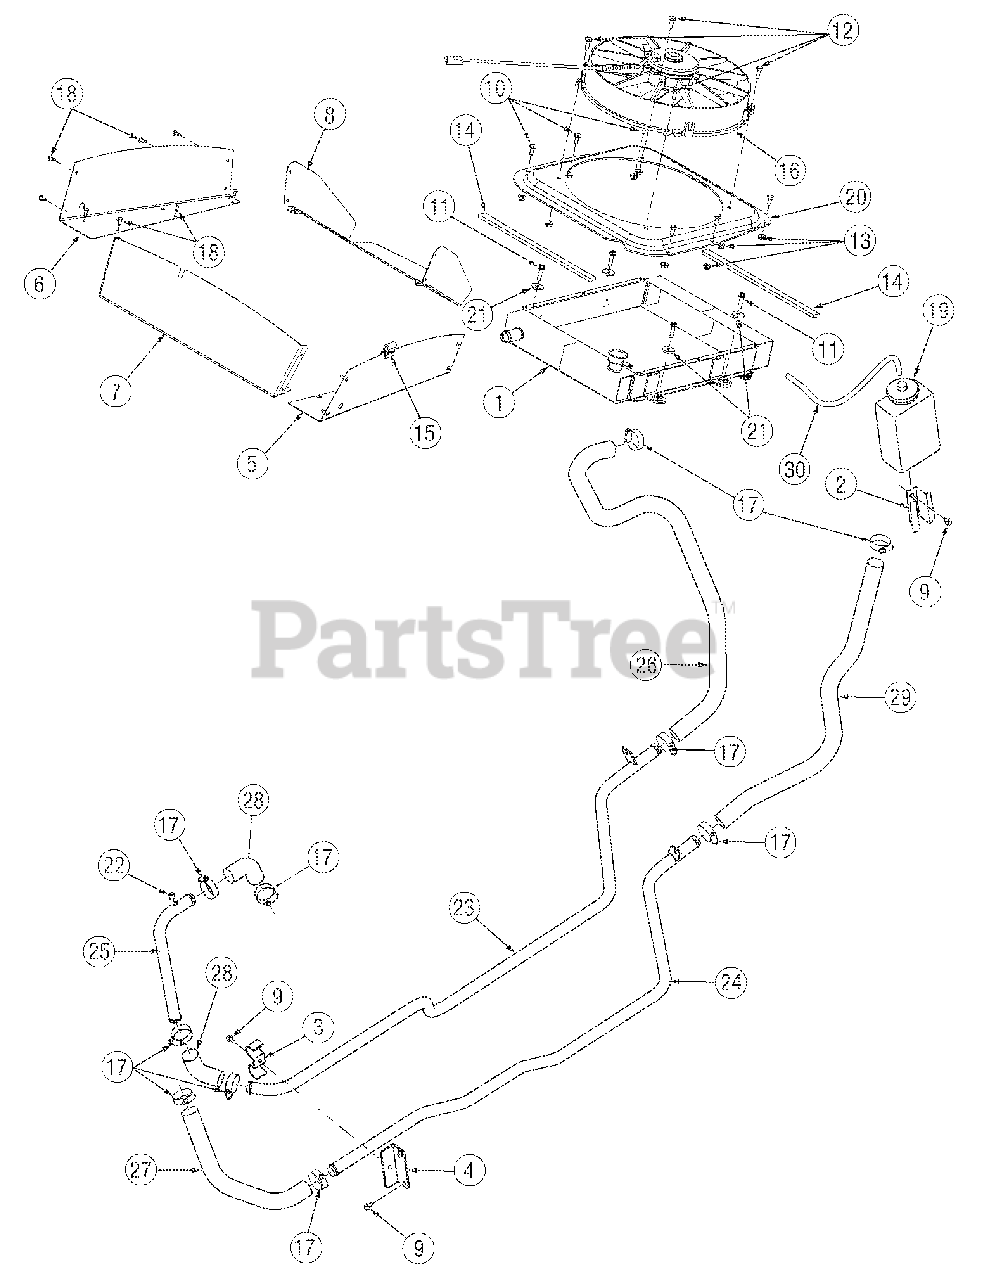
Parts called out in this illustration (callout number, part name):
1	Radiator Asm, zin Core
9	Scr, tt, 1/4-20, 0.500, hxindwsh
10	Hhcs, 1/4-20 x .62 GR5
11	Scr, tt, 1/4-20, 1.000, hxindwsh
12	HHCS, 1/4-20 x .75 GR5
13	Nut, flglk, 1/4-20, grf, nylon
14	Tape, .625 Wide x .25 Thk Foam
15	Heat Baffle Seal
16	Fan, electric, 12v
17	Clamp, hose, adj
18	Pop Rivet 3/16 Dia x .450, sty1
19	Cntnr, over Flow, coolant
20	Shroud, Fan Mount
21	Wash, flat, .265 x .938 x .120
22	Plug, pipe, 1/8-27 Npt, HHCS
27	Hose, rdtr, rr 4x4
28	Hose, rdtr, rr 4x4
29	Hose, rdtr, frt 4x4
30	Tube, overflow, rdtr
